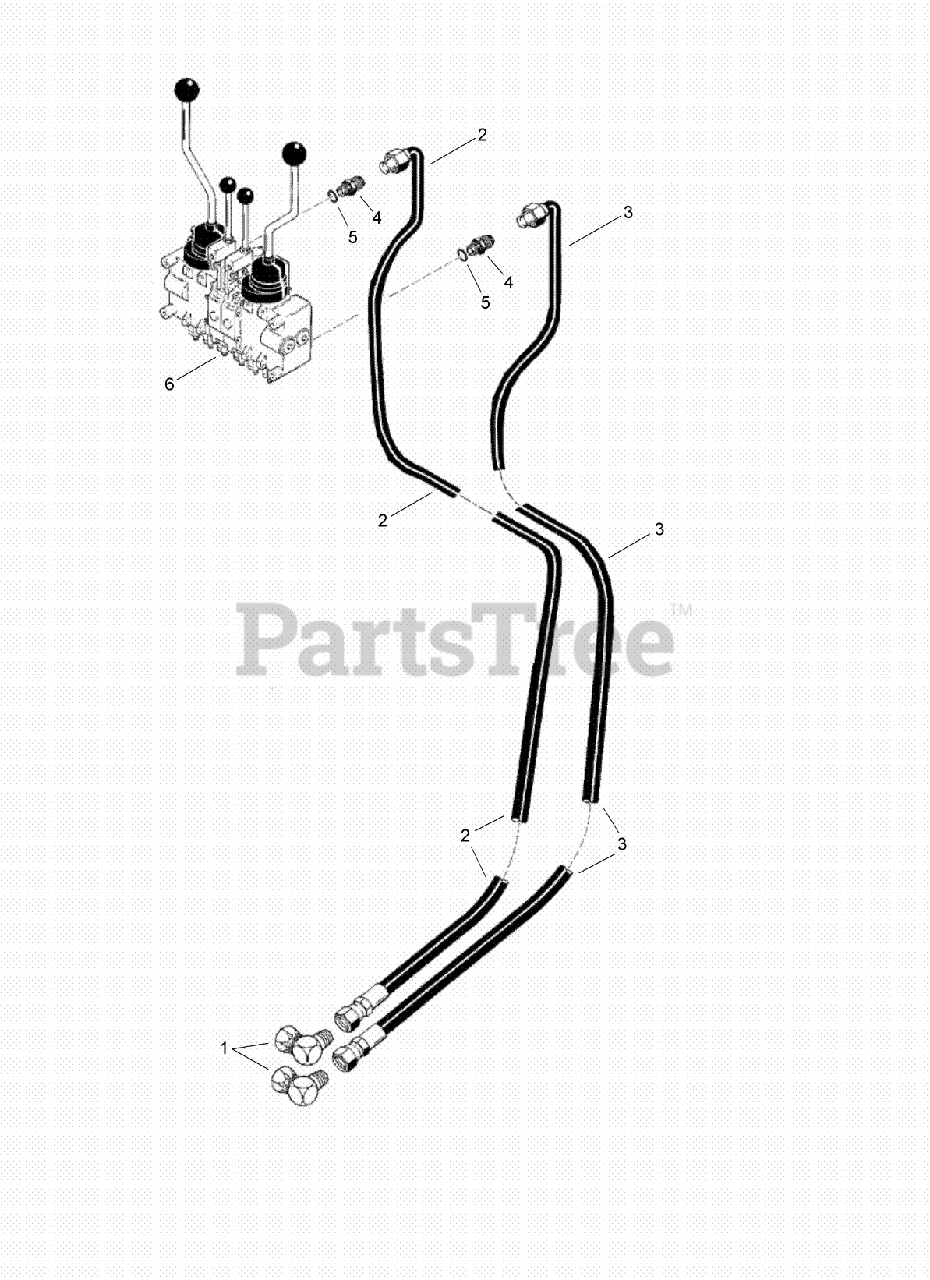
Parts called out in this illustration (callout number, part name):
1	FITTING-ELBOW, 90
2	HOSE-backhoe control valve supply
3	HOSE-backhoe control valve return
4	CONNECTOR-Str Thd 3/4, 37FL-ORB 5/8
5	O-RING
6	HYD CONTROL VALVE ASM
